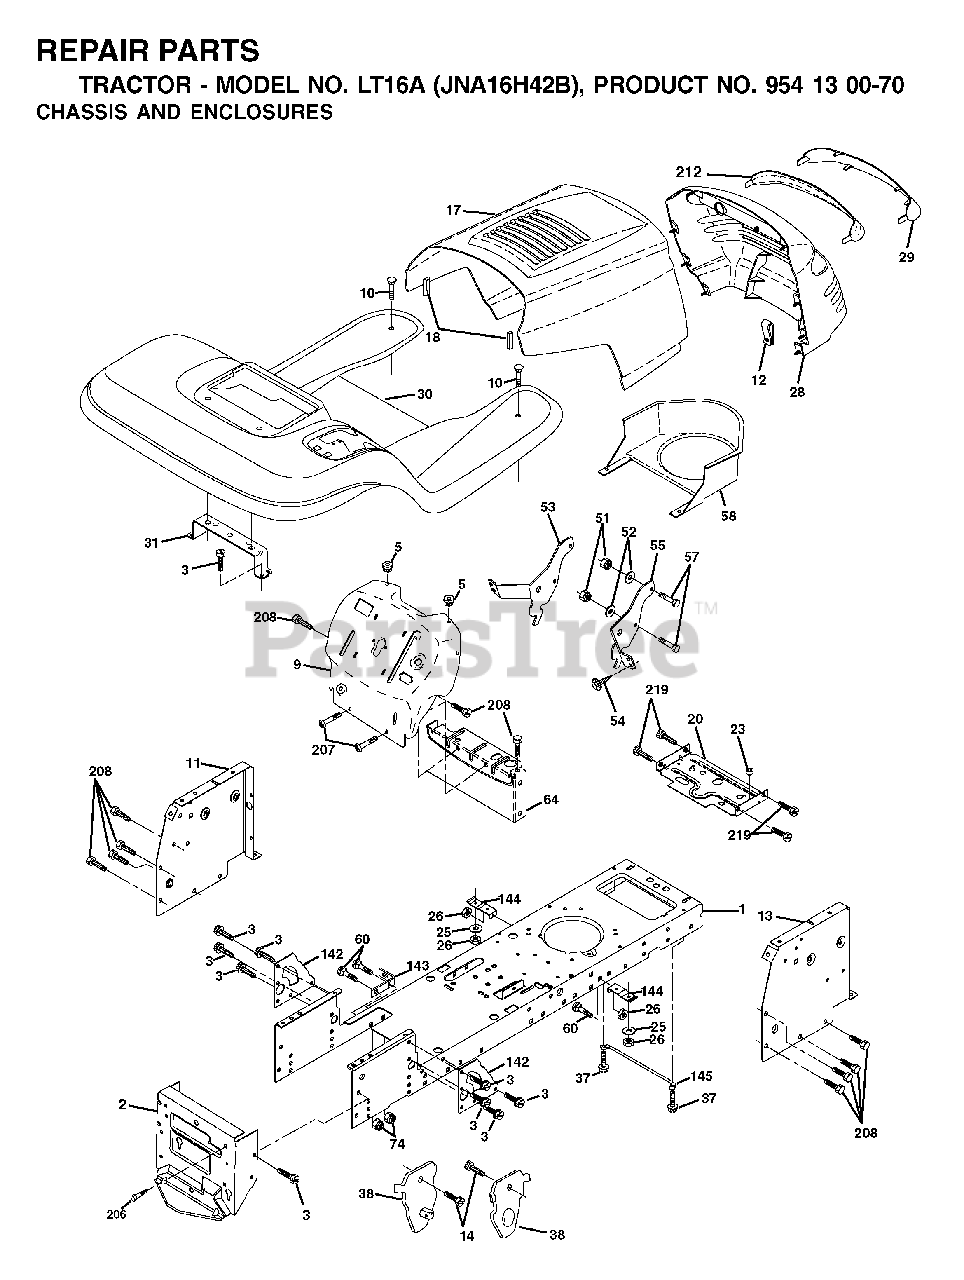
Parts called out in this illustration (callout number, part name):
1	CHASSIS STAMPING
2	DRAWBAR, 12GA
3	SCREW 3/8-16X3/4
5	BUMPER.RUBBER.HOOD
10	BOLT D
11	PANEL.DASH.LH.LTX
13	PANEL ASM, DASH RH
18	BUMPER HOOD T
20	PLATE MTG.BATTERY/FUEL TANK
23	GROMMET T
25	WASHER
26	NUT
28	GRILL/LENS ASM.
38	BRACKET.ASM.PIVOT.MOWER.REAR
51	LOCKNUT
53	BRACKET.GRILLE.LH
57	BOLT
58	AIR DUCT P/L/LT
64	DASH LOWER
74	LOCKNUT
142	PLATE REINFORCEMENT
143	BRACKET, SWAY BAR
144	BRKT, FOOT REST
145	ROD PIVOT CHASSIS/HOOD
206	SHOULDER BOLT 5/16-18TT
207	SCREW, 5/16-18 X 1/2
208	SCREW 3/8-16X1/2
219	SCREW
